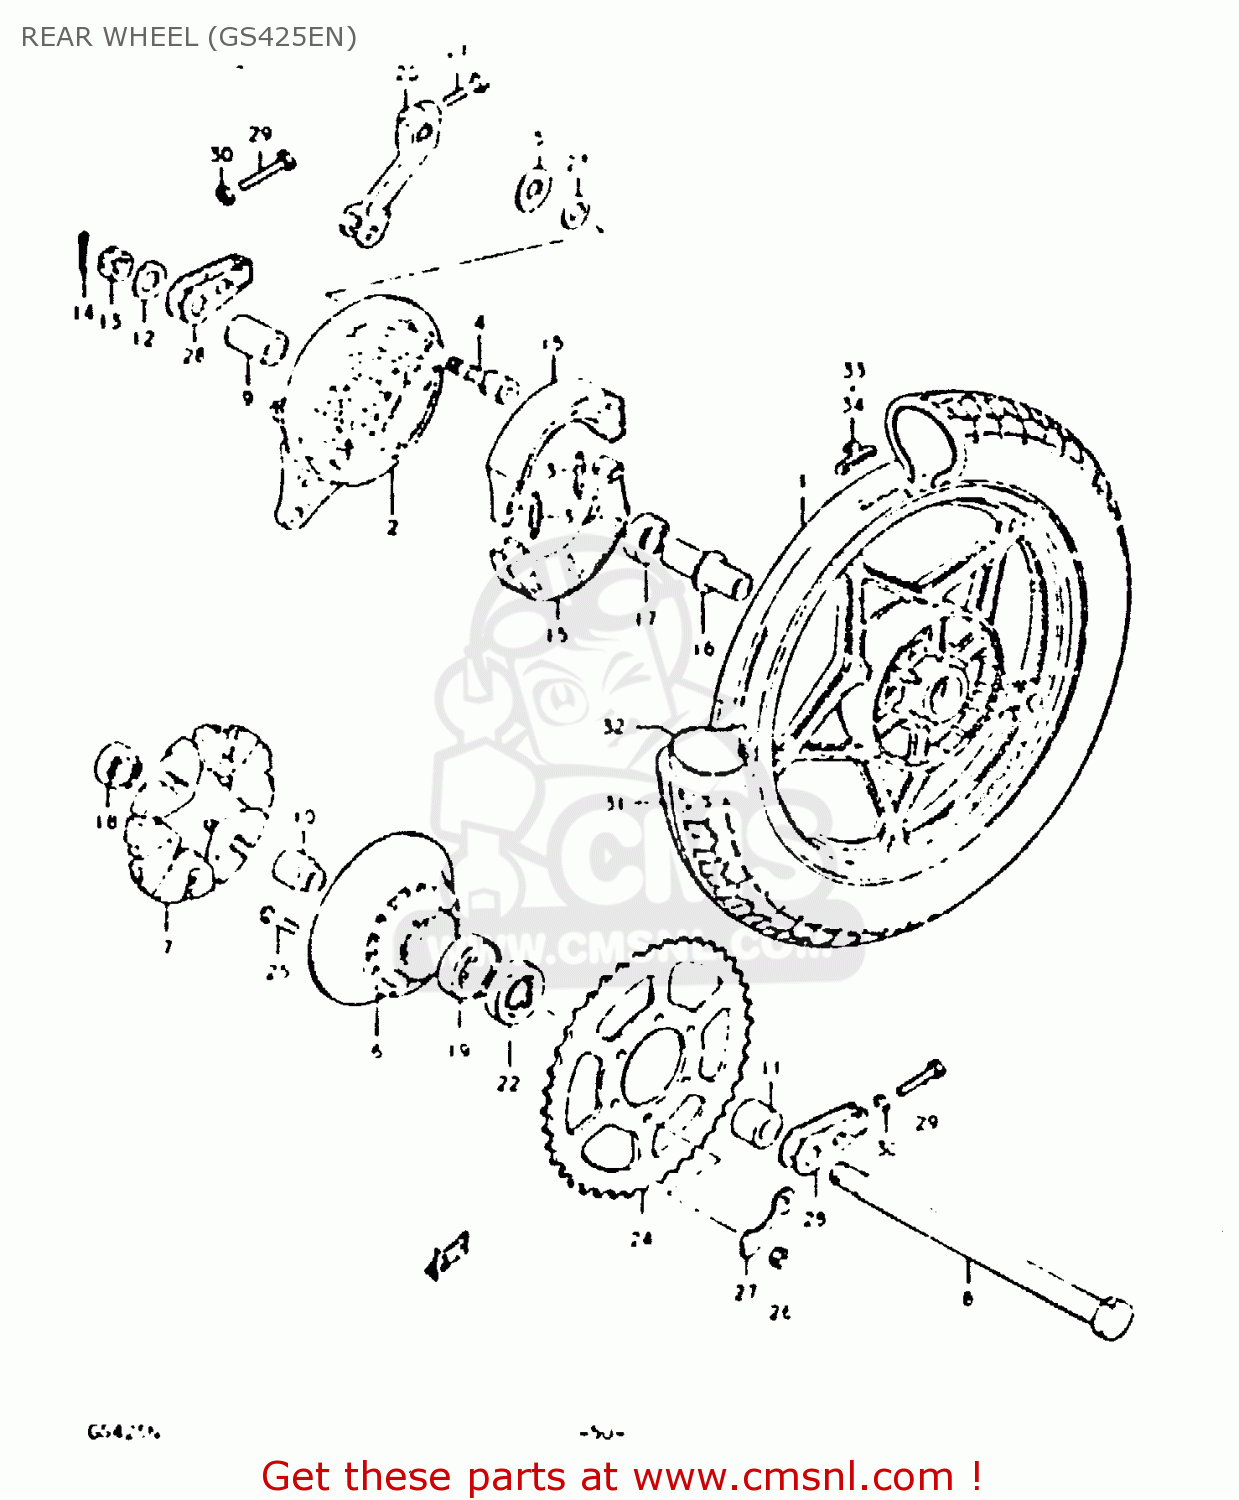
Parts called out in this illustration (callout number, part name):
1	WHEEL,REAR
2	PANEL,REAR HUB
3	SPRING,BRAKE SHOE
4	CAM,FRONT BRAKE
5	WASHER (15X24X1.6)
6	DRUM,REAR SPROCKET MOUNT
7	ABSORBER,RR HUB SHOCK
8	AXLE,REAR
9	SPACER(17.5X28X44.8)
10	SPACER,REAR HUB BEARING
11	SPACER(17X30.5X22.3)
12	WASHER (17X30X3.2)
13	NUT
14	PIN,COTTER
15	SHOE SET,BRAKE
16	SPACER
17	BEARING
18	BEARING
19	BEARING
20	LEVER,REAR BRAKE CAM
21	BOLT
22	OIL SEAL
23	O-RING,BOSS
24	SPROCKET,RR
25	BOLT
26	NUT
27	WASHER
28	ADJUSTER,CHAIN
29	BOLT
30	NUT
31	TIRE
32	TUBE ASSEMBLY,WHEEL,INNER
33	BALANCER,WHEEL
34	BALANCER,WHEEL
